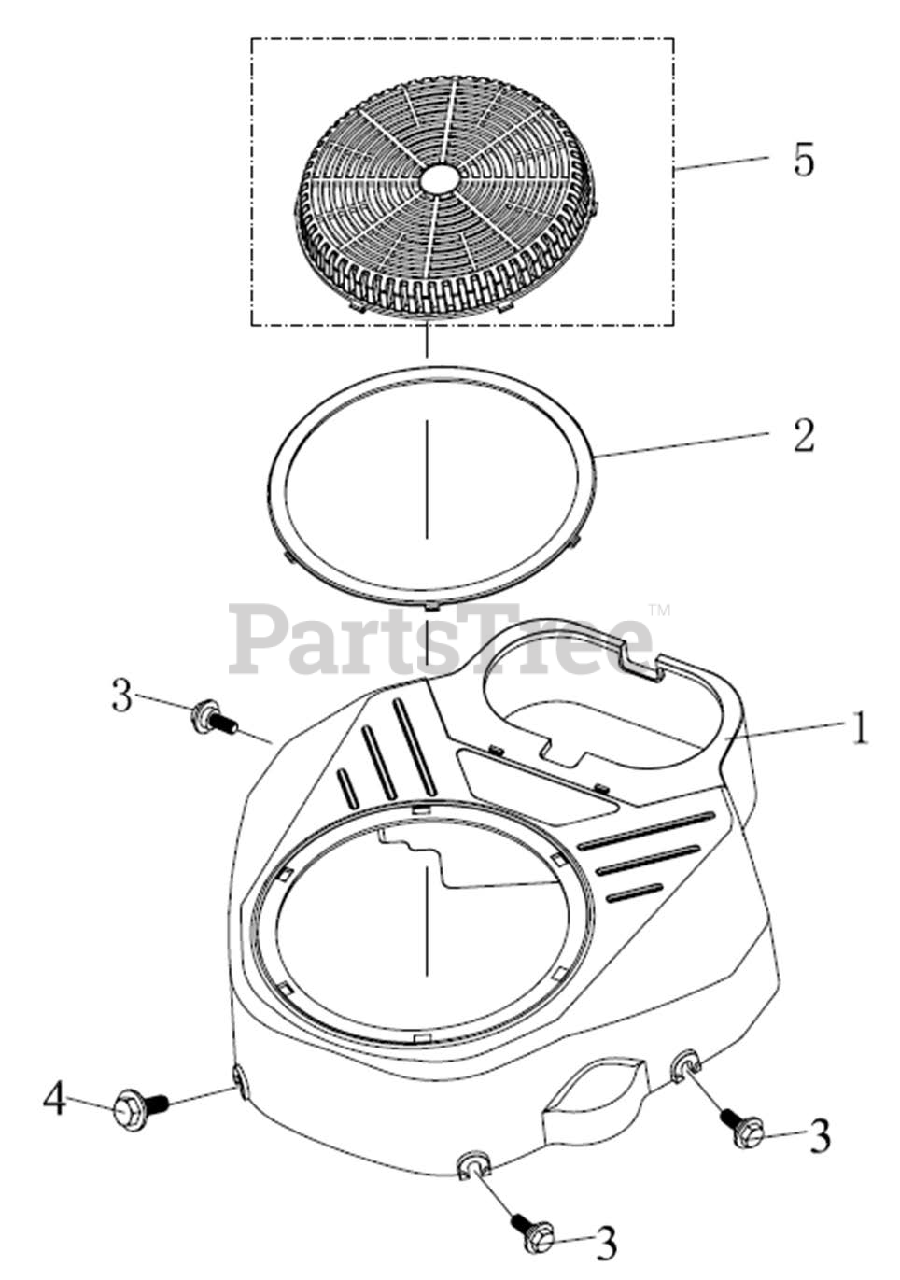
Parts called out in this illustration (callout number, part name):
1	FAN COVER COMP.
3	HEXAGON SHAFT SHOULDER BOLT
4	HEXAGON SHAFT SHOULDER BOLT
5	STARTER OUTER COVER
